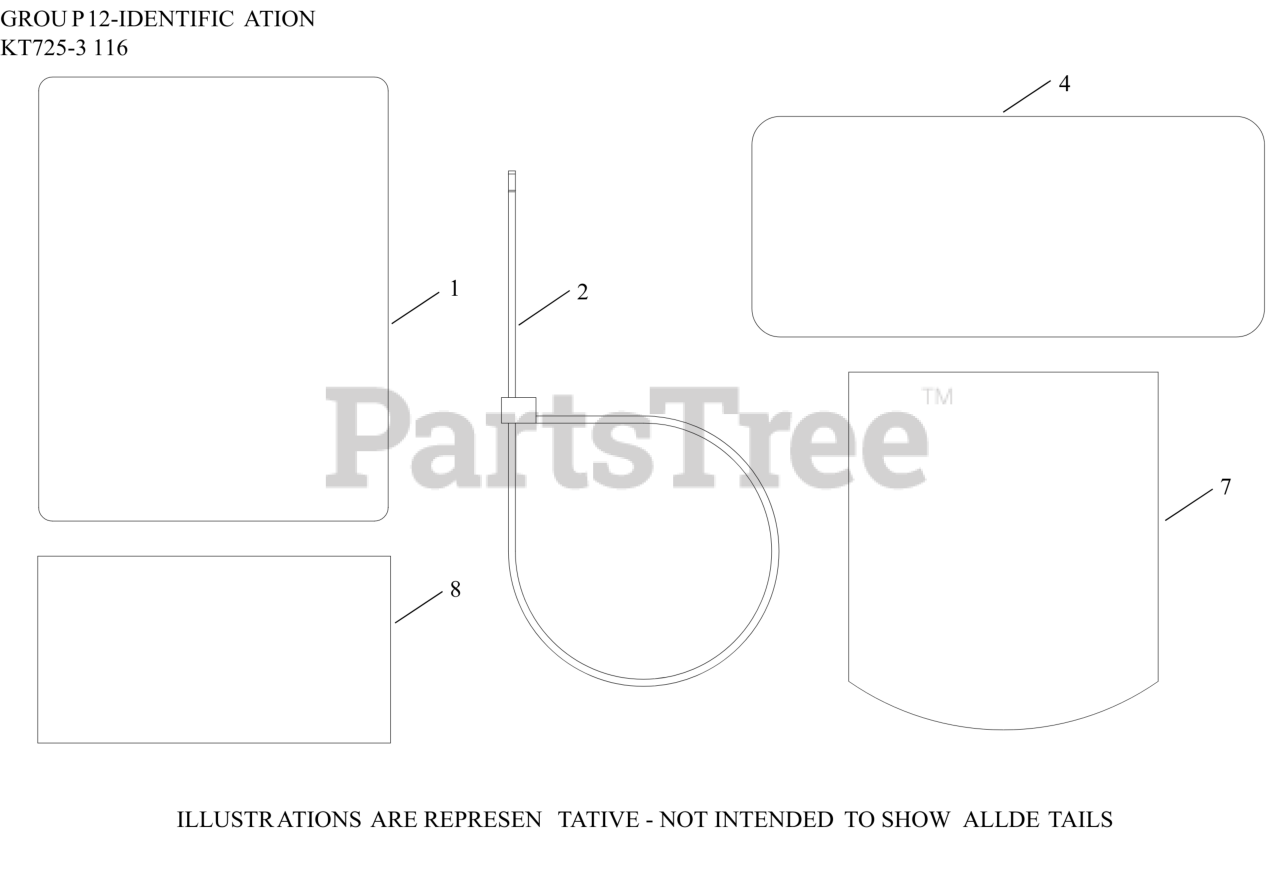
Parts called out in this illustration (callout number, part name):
1	LABEL, CLEAR LAMINATION
4	LABEL, CANADIAN COMPLIANCE
7	LABEL, 7000 SERIES KT725 (22 HP,PRO A/F)
8	DECAL, USA
